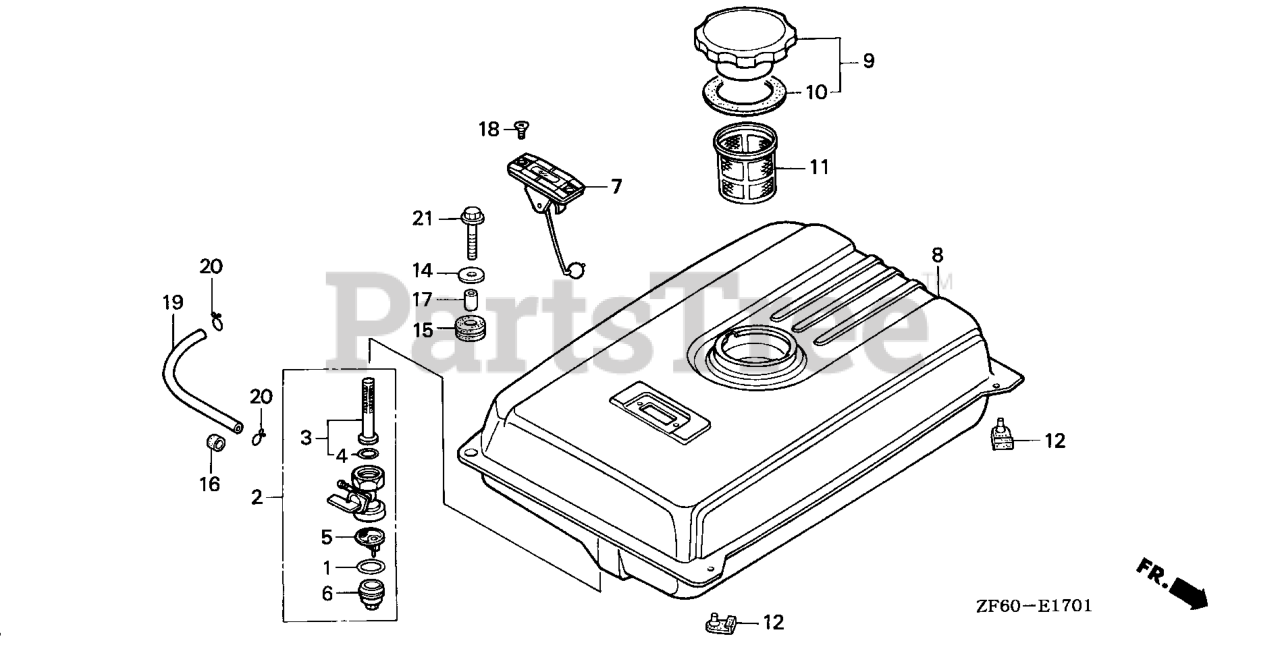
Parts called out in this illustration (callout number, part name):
1	GASKET, FUEL STRAINER CUP
2	PETCOCK ASSY.
3	SCREEN SET, FUEL STRAINER
4	O-RING (9.0X1.3)
5	FILTER, CUP
6	CUP, FUEL STRAINER
12	RUBBER, TANK MOUNTING
16	RUBBER, FUEL (9X15X10)
19	BULK HOSE, FUEL (4.5X3000) (Honda Code 5137104). (4.5X140)
20	CLIP, TUBE (B8)
